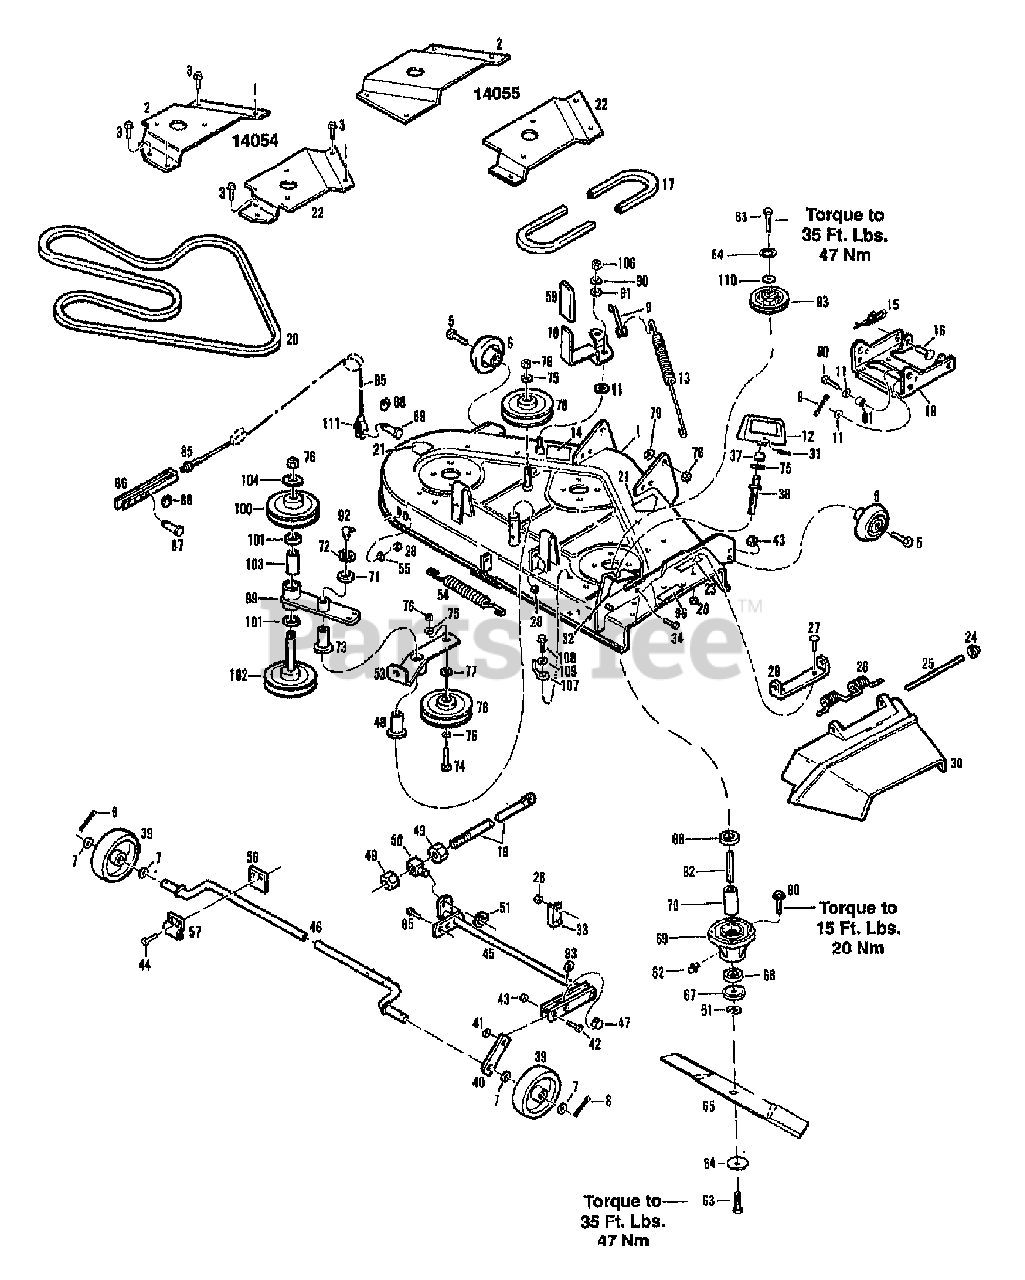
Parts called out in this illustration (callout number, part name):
1	ASSM-MOWER DECK W/DECALS {14054}
1	ASSM-MOWER DECK W/DECALS {14055}
2	COVER-BELT LH {14054}
2	COVER-BELT LH {14055}
3	SCR 1/4-20X.5 FL SELF TAP
5	SCR-SHLDR 3/8-16
6	WHEEL-GAGE
7	WASHER-1.38 X.765X .06 ZP
8	PIN-COTTER .120X1.25 ZP
9	ROD-IDLER
11	WASHER-.5 DIA
12	HANDLE-HEIGHT ADJ
13	SPRING-EXTENSION
14	DECAL-BELT DRIVE
15	RING-COTTER
16	PIN-CLEVIS .62X2.50 ZP
17	BELT-V
18	ASSM-MOWER SUPPORT
19	ROD-ADJUSTING
20	BELT-V {14054}
20	BELT-V {14055}
21	DECAL-OPEI CAUTION
22	COVER-BELT RH {14054}
22	COVER-BELT RH {14055}
23	DECAL-CUTTING LINE
24	NUT-PUSH 3/8 ZP
26	SPRING-TORSION
27	BOLT-CARR 5/16-18X.63 ZP
28	NUT-TOP/LK 5/16-18 ZP
30	DEFLECTOR-DISCHARGE
31	PIN-ROLL .188X1.0
32	DECAL-HEIGHT ADJUST
33	RETAINER-SHAFT
34	SCR-HH 5/16-18X.63 G5
37	SPACER-HANDLE
38	ROD-ADJUSTING
39	GAUGE-WHEEL
40	LINK-WHEEL SUPT
41	SPACER-.75X.39X.545
42	SCR-HH 3/8-16X1.5 G5 ZP
43	NUT-LOCK 3/8-16
44	SCR-HH 5/16-18X1.0 G5 ZP
45	ARM-HEIGHT ADJUST
46	SUPT-WHEEL SHAFT
47	PIVOT-ADJUSTING SCR
48	BEARING-FLANGE
49	NUT-HEX
50	BLOCK-PIVOT
51	RING-RETAINING EXT .694 ID
54	SPRING-EXT
55	WASHER-LOCK
56	PLATE-DOUBLER
57	SUPPORT-SHAFT
60	SCR-HFLK 5/16-18X.75
62	FITTING-GREASE 1/4-28X2.00
63	SCR-HH 1/2-14X1.00
64	WASHER-BELLEVILLE
65	BLADE-CUTTER {14054}
65	BLADE-CUTTER {14055}
65	BLADE-LIFT {14054}
65	BLADE-LIFT {14055}
67	SPACER-BLADE
68	BEARING-BALL
69	HOUSING-SPINDLE
71	SHIM-WASHER
72	RING-RET. EXT .875 ID
73	FLANGE-BEARING
74	SCR-HH 1/2-13X2.0 G5 ZP
75	WASHER-FLAT .88X.5X.06 ZP
76	NUT-TOP LOCK 1/2-13 ZP
78	PULLEY-IDLER
79	WASHER {14055}
80	SCR-HH 1/2-13X1.25 G5 ZP
81	SPACER-TUBULAR
82	SHAFT-SPINDLE
84	WASHER-LK .438 ZP
85	ASSM-CABLE(MOWER DECK)
86	YOKE
87	PIN-CLEVIS .5X1.437 ZP
88	RING-CIRCLE COTTER
89	PIN-CLEVIS .375 X .937 ZP
90	WASHER-.875X.390X.134
91	WASHER-FLAT 1.0X.516X.031 {14054}
91	WASHER-SHIM {14055}
92	FITTING-GREASE 90 DEGREE
93	WASHER-PLASTIC
95	SCR-HHC 5/16-18X.75 GR 5 ZP
96	DECAL-DANGER
99	ASSM-MOUNTING ARM
100	ASSM-SHEAVE & HUB
101	BEARING-BALL
102	ASSM-SHEAVE & SHAFT
106	NUT-H/LK 3/8-24
107	GUIDE-BELT {14055}
108	SCR-FLANGE 1/4-20X3/4 GR5 {14055}
109	WASHER-.75X.312X.065 ZP {14055}
110	WASHER-1.25X.5X.083 ZP
111	CABLE END-CLEVIS
